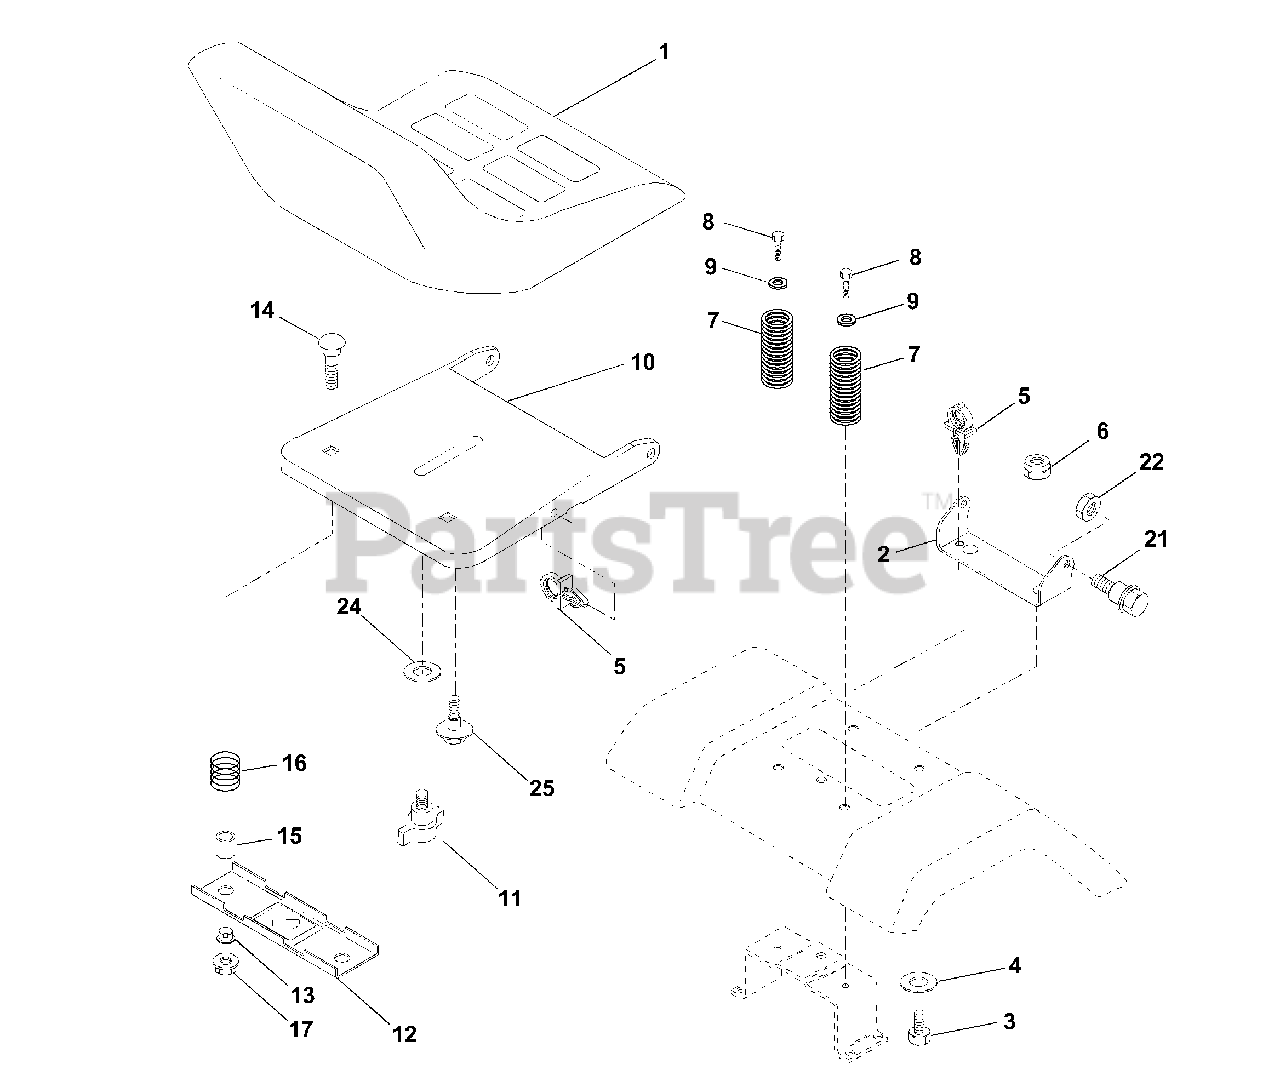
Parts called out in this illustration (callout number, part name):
1	Seat
2	Bracket Pivot Seat 8 720
3	Bolt Fin Hex 3/8-16 Unc X 1
4	Washer 13/32 X 1 X 10 Ga
5	Clip Push-In
6	Nut Hex w/Ins. 3/8-16 Unc
7	Spring Seat Cprsn 2 250 Blk Zi
8	Screw 3/8-16 X 1.5
9	Washer 13/32 X 1 X 14 Ga.
10	Pan Seat
11	Knob Seat
12	Bracket Mounting Switch
13	Bushing Snap Blk Nyl 50 Id
14	Bolt Rdhd Sqnk 1/4-20x1-1/2
15	Spacer Split 28x 88
16	Spring Cprsn
17	Nut Lock 1/4 Lge Flg Gr 5 Zinc
21	Bolt Shoulder 5/16-18 Unc
22	Nut Hex Lock W/Ins 5/16-18
24	Washer 17/32 X 1-3/16 X 12 Ga.
25	Bolt Shoulder 5/16-18 X 62
